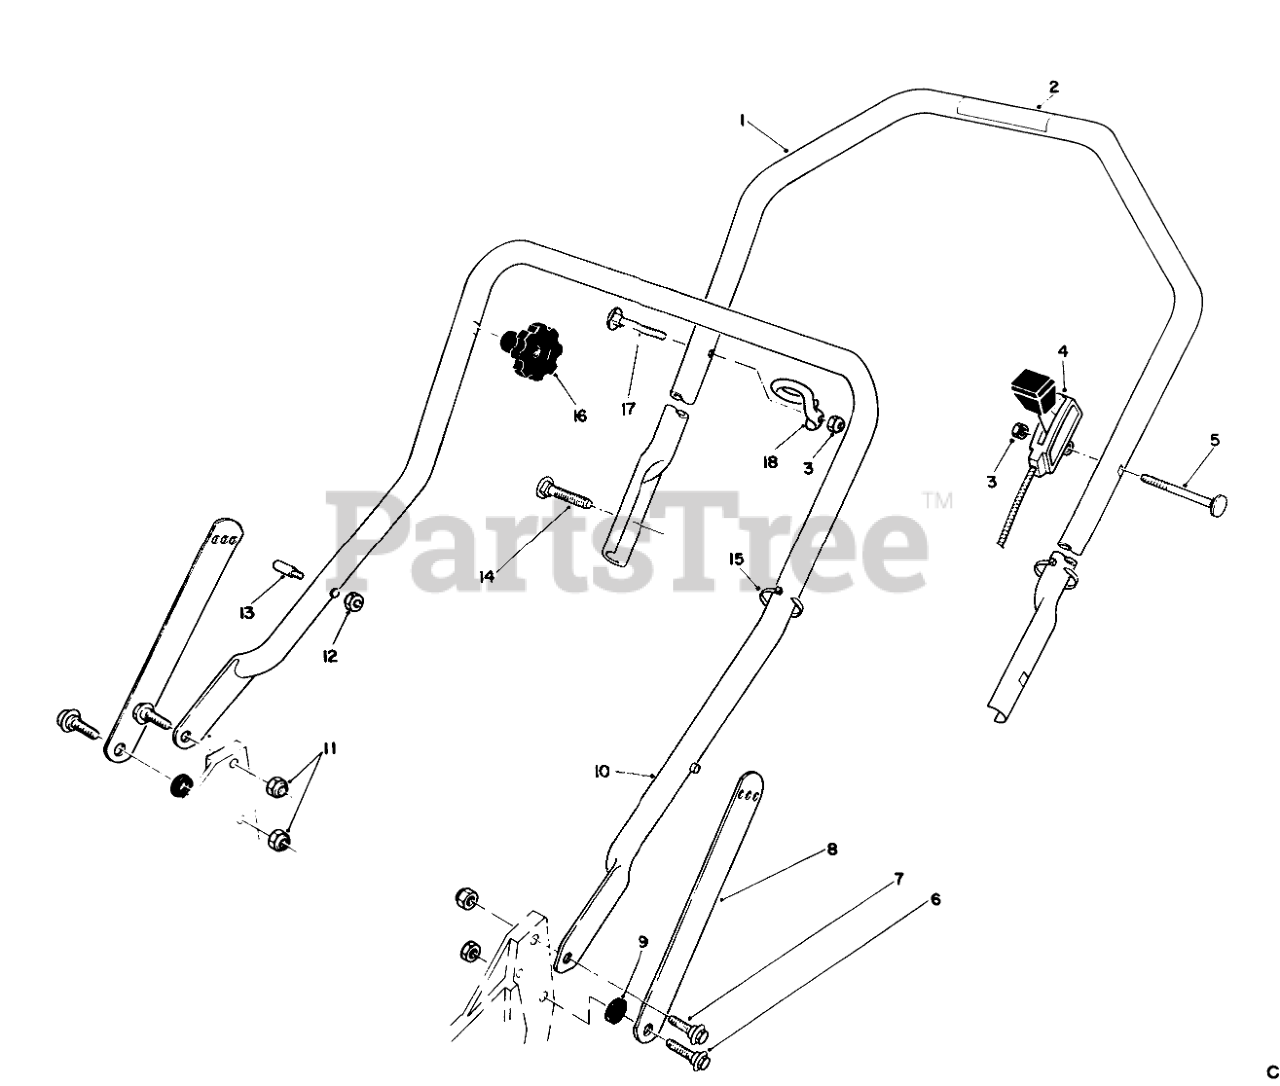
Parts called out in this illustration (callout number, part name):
1	Handle-Upper (Incl Ref. #2)
2	WARNING DECAL
3	NUT-LOCK, NI
4	THROTTLE CONTROL
5	SCREW-HANDLE
6	SCREW-SHOULDER
7	SCREW-SHOULDER
8	Handle Latch
9	SPACER
10	LOWER HANDLE ASM
11	NUT-LOCK, NI
12	NUT-LOCK, NI
13	HANDLE PIN
14	5/16-18 X 2 HNDLE SCREW
15	TIE-CABLE
17	HANDLE SCREW
18	Guide
